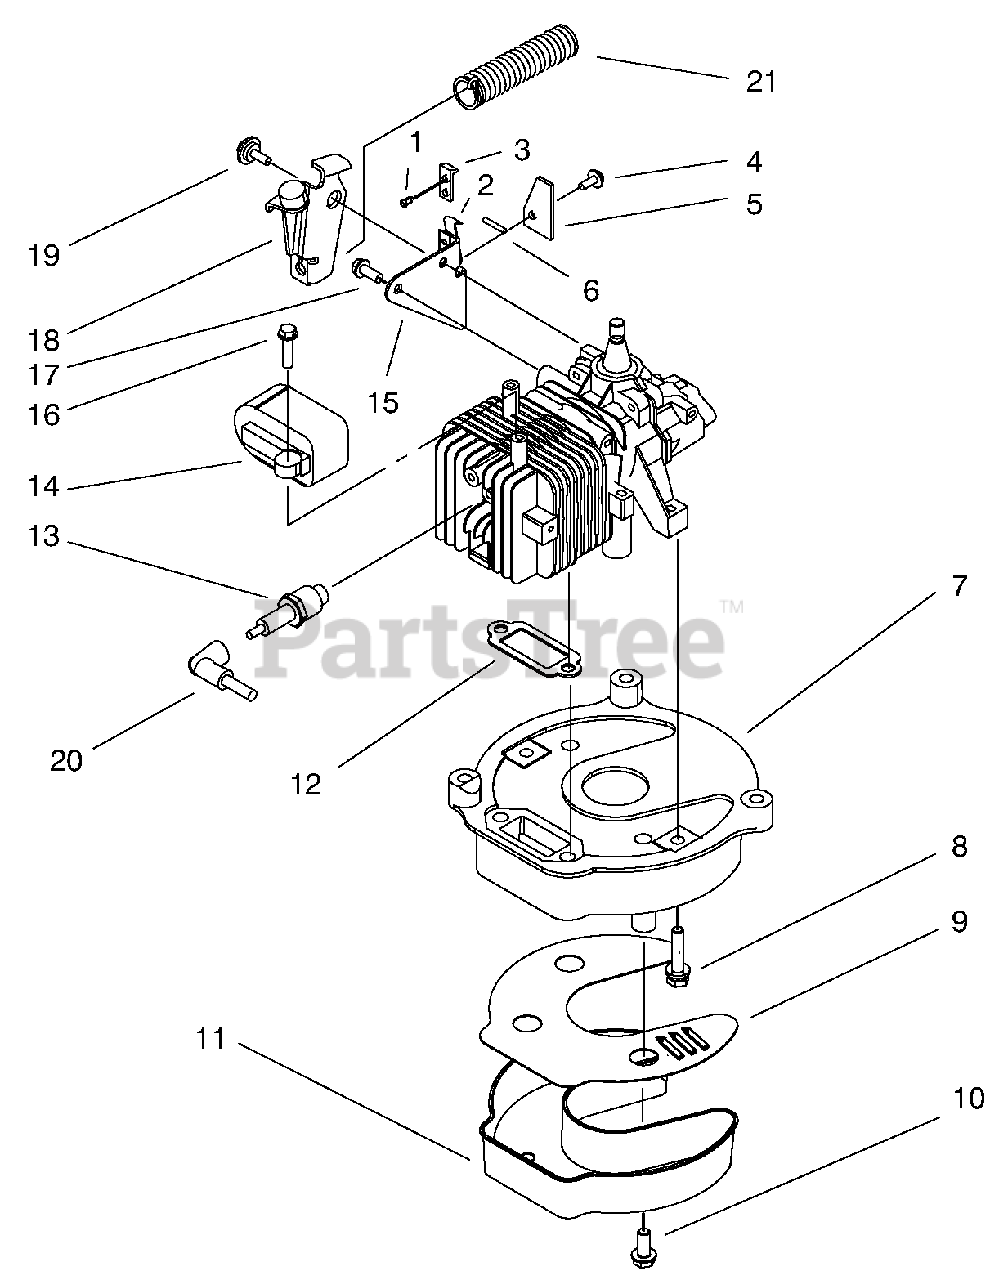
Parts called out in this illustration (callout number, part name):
1	RIVET-PLASTIC
2	STRAP-GROUND
3	STRAP-INSULATION
5	STOP-GROUND STRAP
6	ELECTRICAL LEAD ASM
7	PLATE-MUFFLER V
8	SCREW V
9	BAFFLE-MUFFLER
11	Cover-Muffler
12	GASKET-EXH. VF
13	Plug-Spark
14	Ignition Assembly (Incl. Ref. #20)
15	PLATE-BRAKE
17	SCREW
18	BRAKE PLATE ASM
19	SCREW-SHOULDER
20	HI-TENS.LEAD SM
21	SPRING-COMPRESSION
